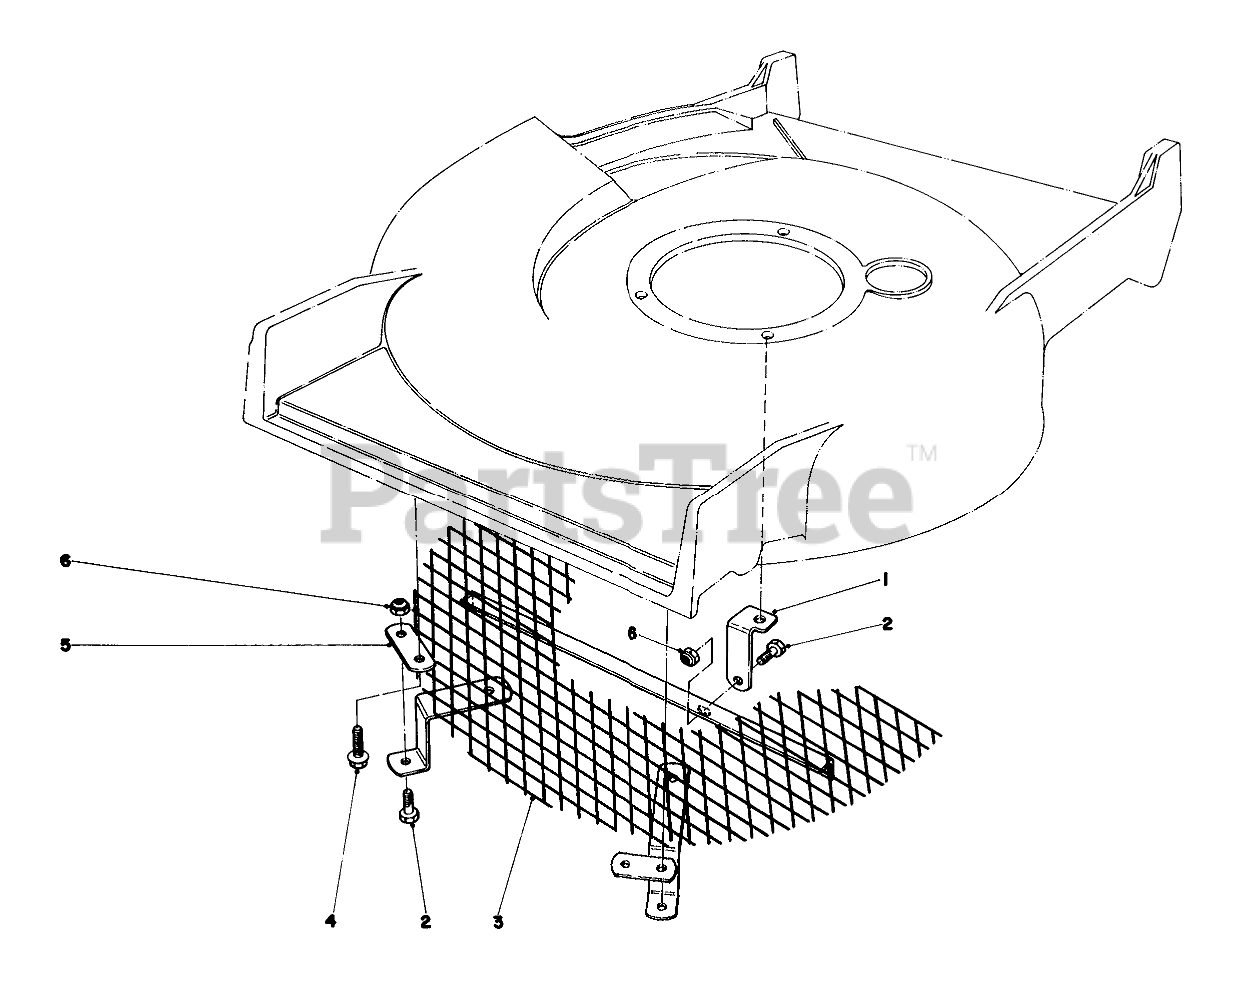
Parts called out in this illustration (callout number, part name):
1	Support Bracket
2	SCREW-HH
3	Screen
4	SCREW-HWHTF
5	ANCHOR
6	NUT-LOCK, NI
